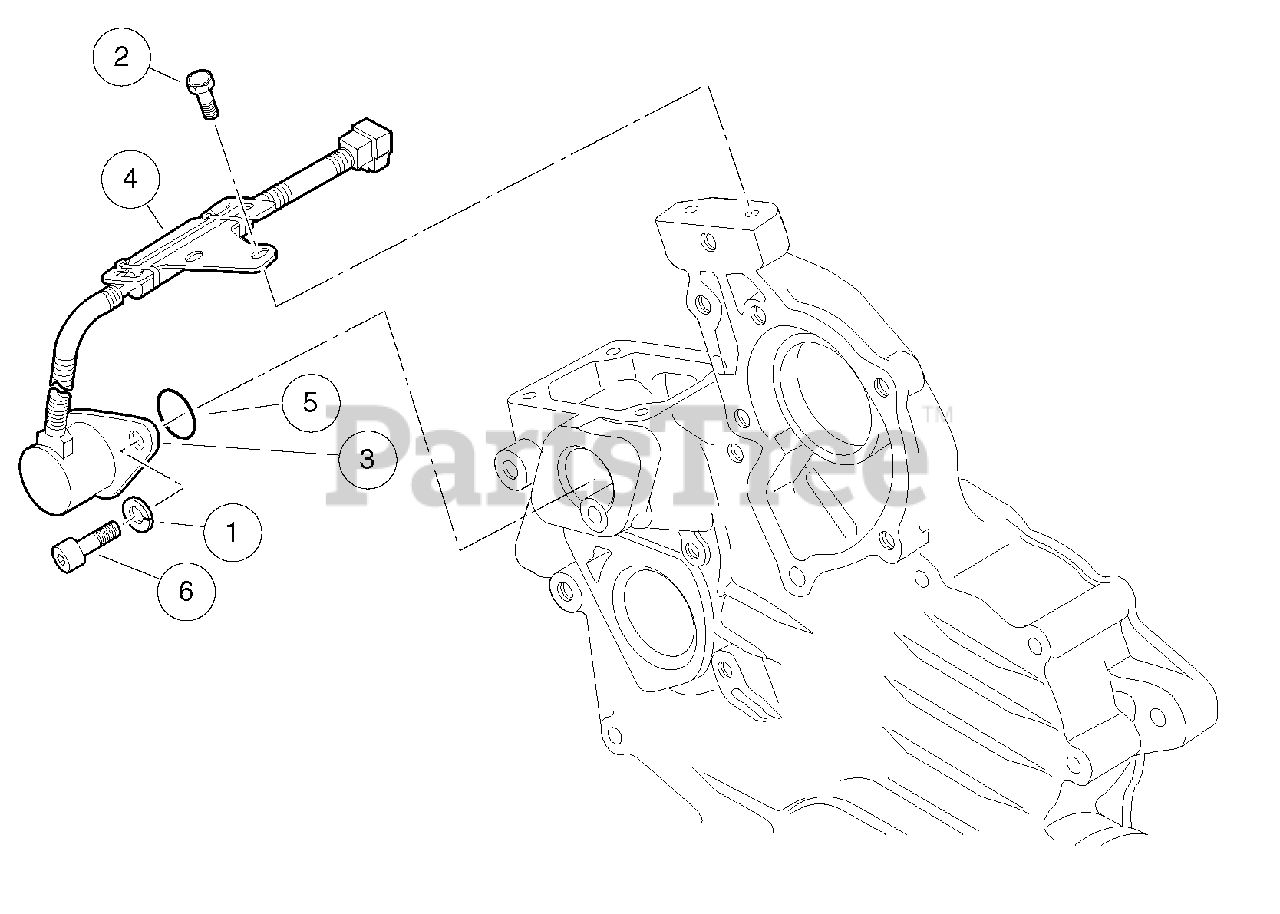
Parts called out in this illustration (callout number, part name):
1	Washer, Spring, M6, D722
2	Bolt, Solenoid, Stop, D722
3	Solenoid, Stop
4	Stay, Stop Solenoid
5	O-Ring, Stop Solenoid
6	Bolt, Stop Solenoid
